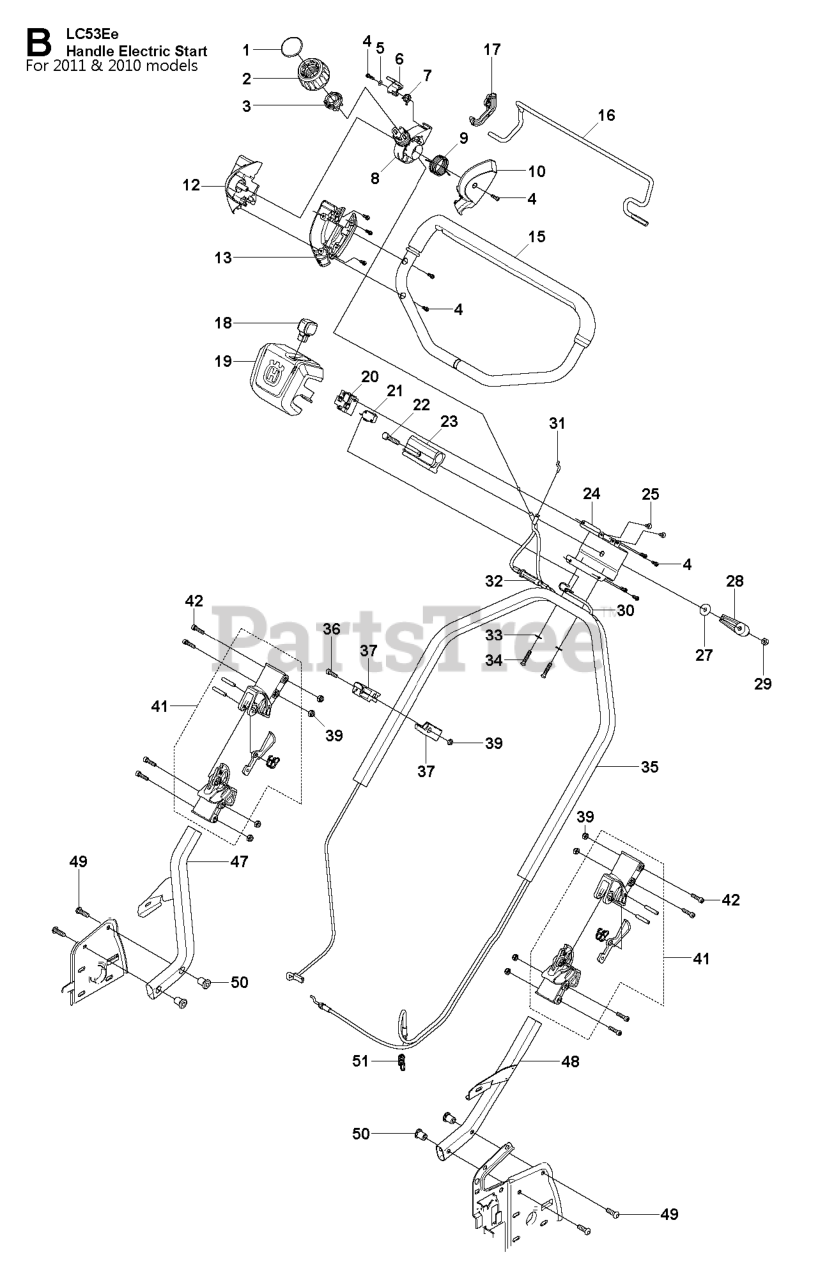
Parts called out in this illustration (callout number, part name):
5	WASHER
25	SCREW ITXPANTT M5X10 ZPB (A00
27	WASHER - 25X8.5X2.3
36	SCREW MC6S 6X20
42	REPL BY 725 53 74-55
